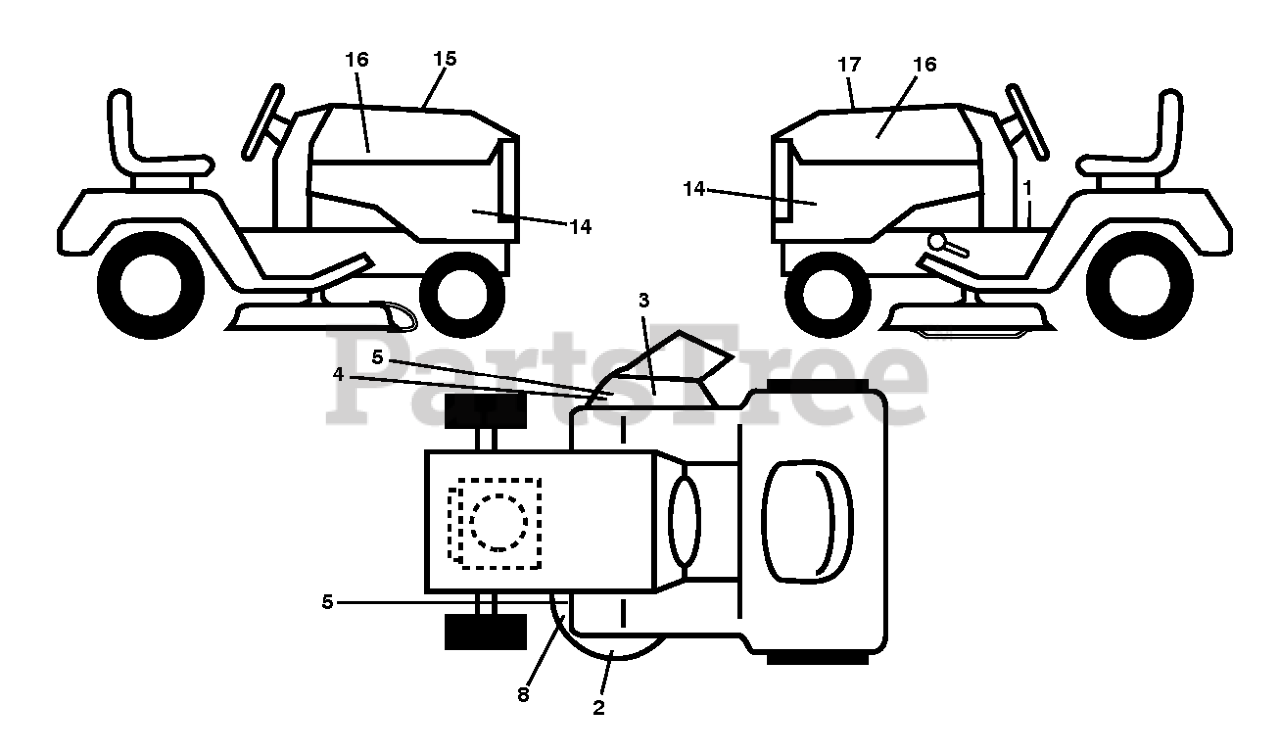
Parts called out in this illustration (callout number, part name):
1	DECAL.FENDER.WARNING.ENGLISH
2	DECAL DECK DECAL DECAL.54DECK.
3	DECAL.TRACT/ZTR.DECKWARN.HUSQ
4	DECAL BELT ROUTING DECAL DECAL
5	DECAL.DECK.CLEARCUT.NOSTEP
8	DECAL DECK DECAL DECAL.DECK.WA
14	DECAL.SDPNL.LGT54DXL.SET.R/L
15	DECAL.WARNING.CUST.RESP.E85.
16	DECAL.BADGE.170MM.TEXTLOGO.
17	DECAL.RPL.KH.KT7.TGB.54F.K46L
